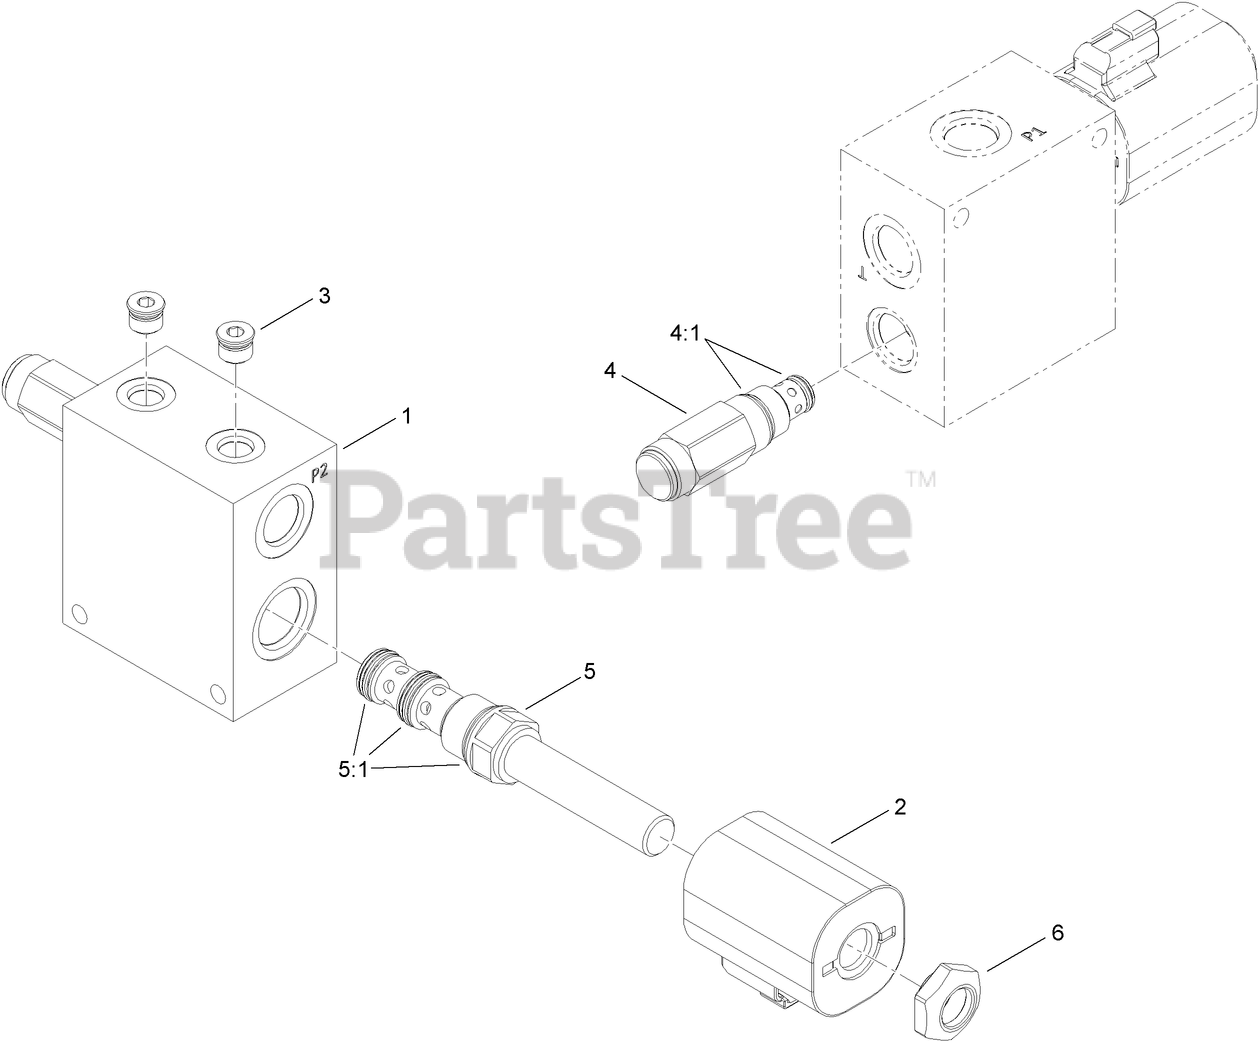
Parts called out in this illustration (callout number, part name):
1	BLOCK-MANIFOLD
2	E-COIL, 12V DC
3	Plug
4	VALVE-RELIEF
4:1	SEAL KIT
5	VALVE-SOLENOID
5:1	SEAL KIT
6	NUT-COIL
